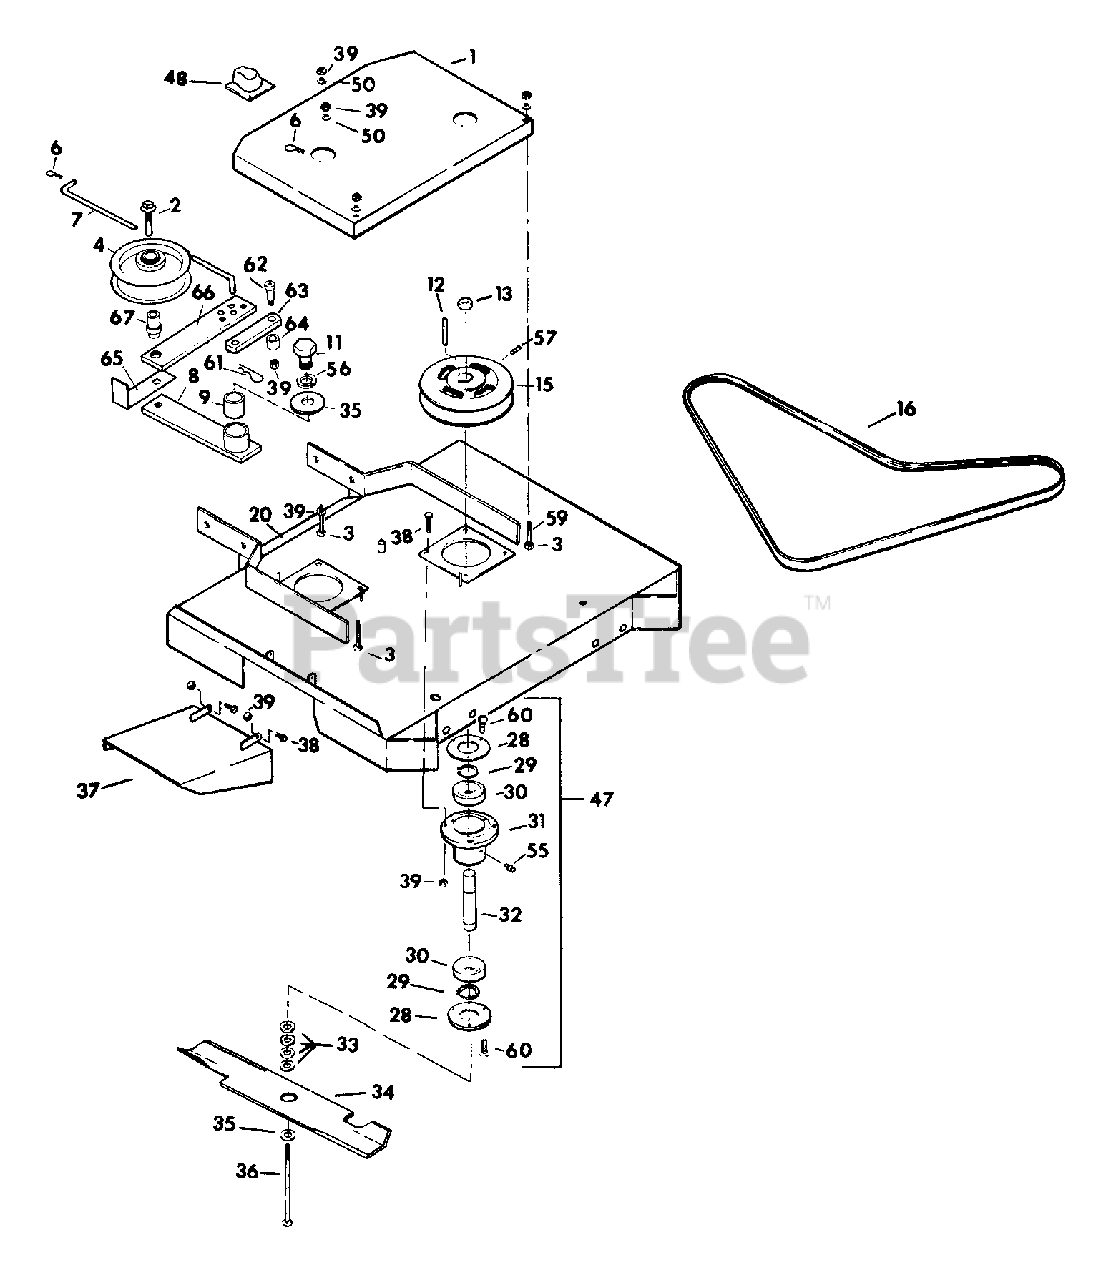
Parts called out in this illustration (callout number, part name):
1	Belt Shield w/Decal
2	3/8"-16x1-3/4" Whizlock Bolt
3	5/16"-18 Whizlock Nut
4	Heavy Duty Idler Pulley
6	#2 Hairpin Cotter
7	Lower Blade Drive Linkage
8	Idler Arm Assembly Complete w/Brg (P/N 76452)
9	Oilite Bearing
11	5/8"-11x1" Hex Hd. Cap Screw
12	1/4" Sq. x 1-1/4" Machine Key
13	5/8"-18 Hex Nut
15	Pulley w/Set Screws (P/N 76956)
16	Belt
20	Front Deck w/Decals
28	Cutter Housing Cap
29	Snap Ring
30	Cutter Housing Bearing
31	Cutter Housing
32	Cutter Spindle
33	Blade Spacer
34	(.164") Ultra High Lift Blade-18"
34	(.250") Ultra High Lift Blade-18"
35	5/8" SAE Washer
36	5/8"-18x7-1/2" Hex Hd. Cap Screw-Grade 5
37	Chute Assembly
38	5/16"-18x1" Hex Hd. Cap Screw
39	5/16"-18 Nyloc Hex Nut
47	Complete Cutter Housing Assembly
48	Shaft Guard
50	5/16" Std. Flat Washer
55	1/8" NPT Straight Zerk
56	5/8" Lock Washer
57	5/16"-18x3/8" Nyloc Knurled Cup Point Set Screw
59	5/16"-18x3-1/4" Hex Hd. Tap Bolt-Grade 5
60	#10-24x3/8" Pan Hd. Slt. Mach. Screw
61	#4 Hairpin Cotter
62	3/8"x3/4" Knurled Socket Hd. Shoulder Bolt
63	Assist Arm
65	Belt Snubber
66	Tightening Arm
67	Engagement Flange Bushing
